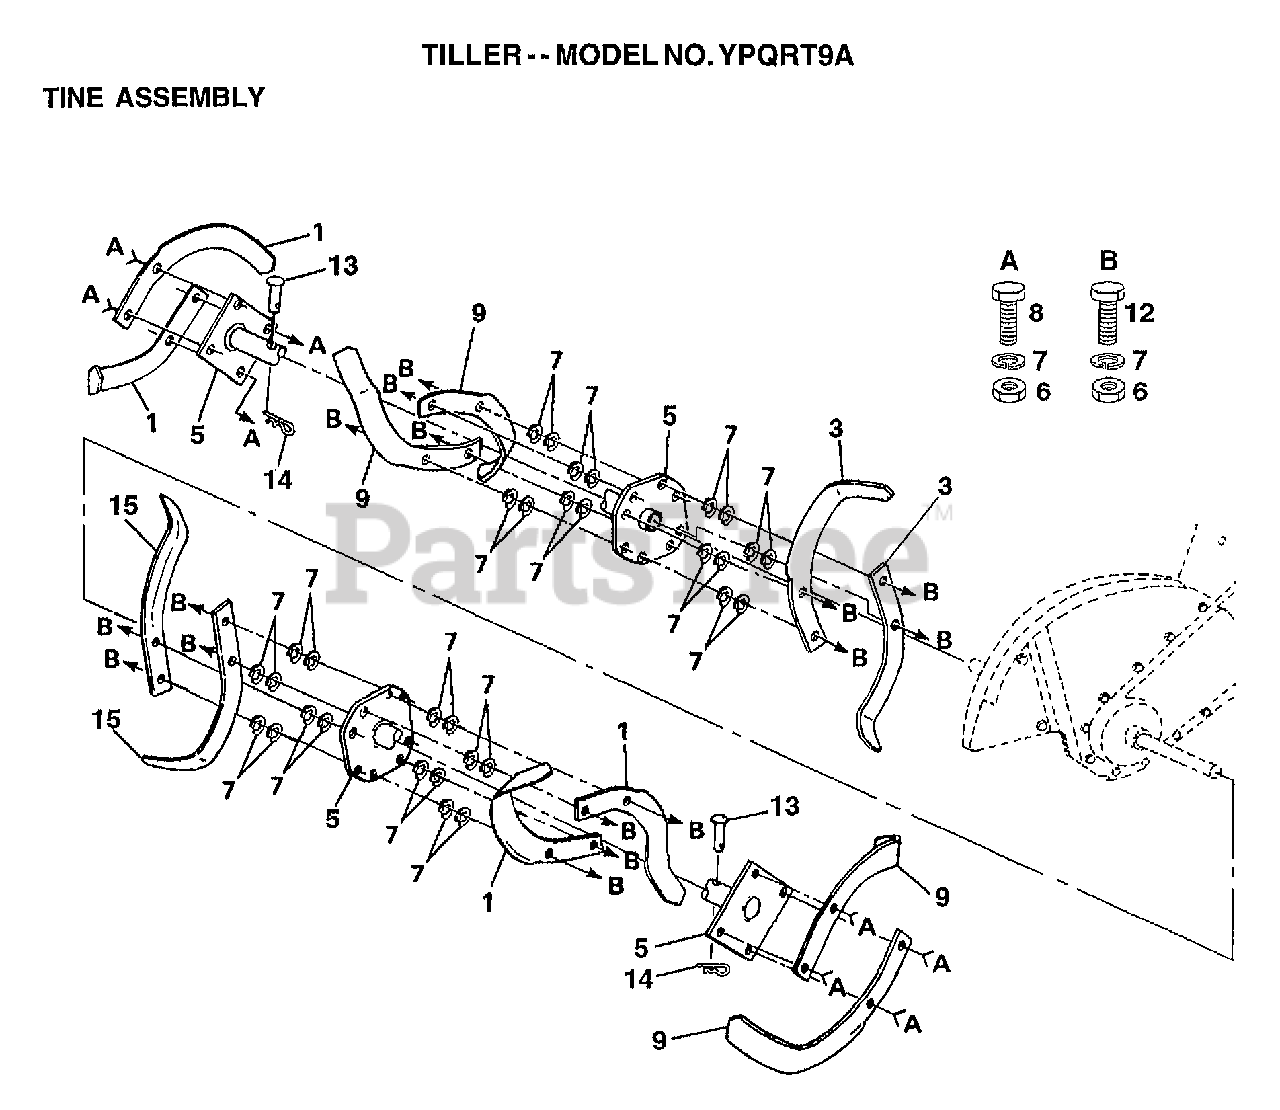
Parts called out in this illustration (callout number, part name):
3	TINE.LH.CRT
5	TINE ASSY CRT
7	LOCKWASHER
8	BOLT
12	BOLT.3/8-24X1-1/2
13	RIVET.PAN HD.1.75
14	RETAINER.SPRING
15	TINE RH CRT
